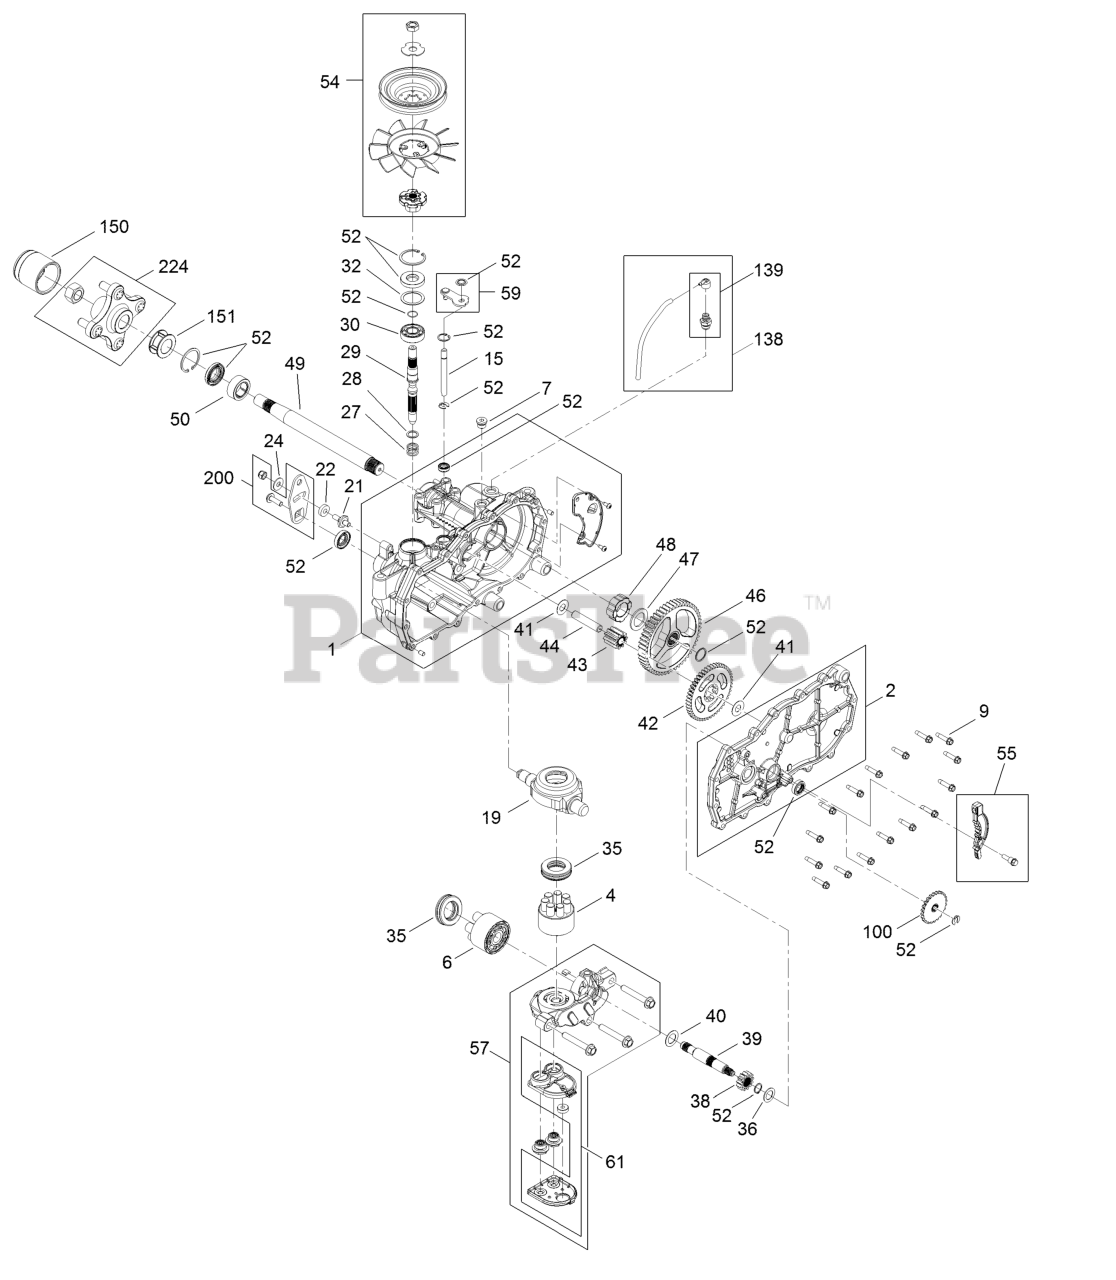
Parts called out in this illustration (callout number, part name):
1	MAIN HOUSING ASM
2	SIDE ASM
4	PUMP BLOCK ASM
6	CYLINDER BLOCK KIT
7	PLUG-THREAD, STRAIGHT
9	SCREW-HHF
15	ROD-BYPASS
19	SWASHPLATE-TRUNNION
22	PUCK-FRICTION
29	SHAFT-INPUT
30	BEARING-BALL
35	BEARING-THRUST
36	WASHER-FLAT
38	GEAR-PINNION, 13T
39	SHAFT-MOTOR
41	Washer
42	GEAR-10T/48T
43	GEAR-JACKSHAFT, 10T
44	PIN-JACKSHAFT
46	GEAR-52T, BULL
48	BEARING-SLEEVE
49	SHAFT-AXLE
50	BUSHING-AXLE
54	FAN PULLEY KIT
55	BRAKE ARM KIT
57	CENTER SECTION FILTER KIT
59	BYPASS KIT
61	FILTER KIT
100	DISC-BRAKE, COG
138	BREATHER KIT
139	BREATHER ASM
150	COVER-NUT, AXLE
151	TUBE-AXLE
200	CONTROL ARM KIT
224	HUB KIT
